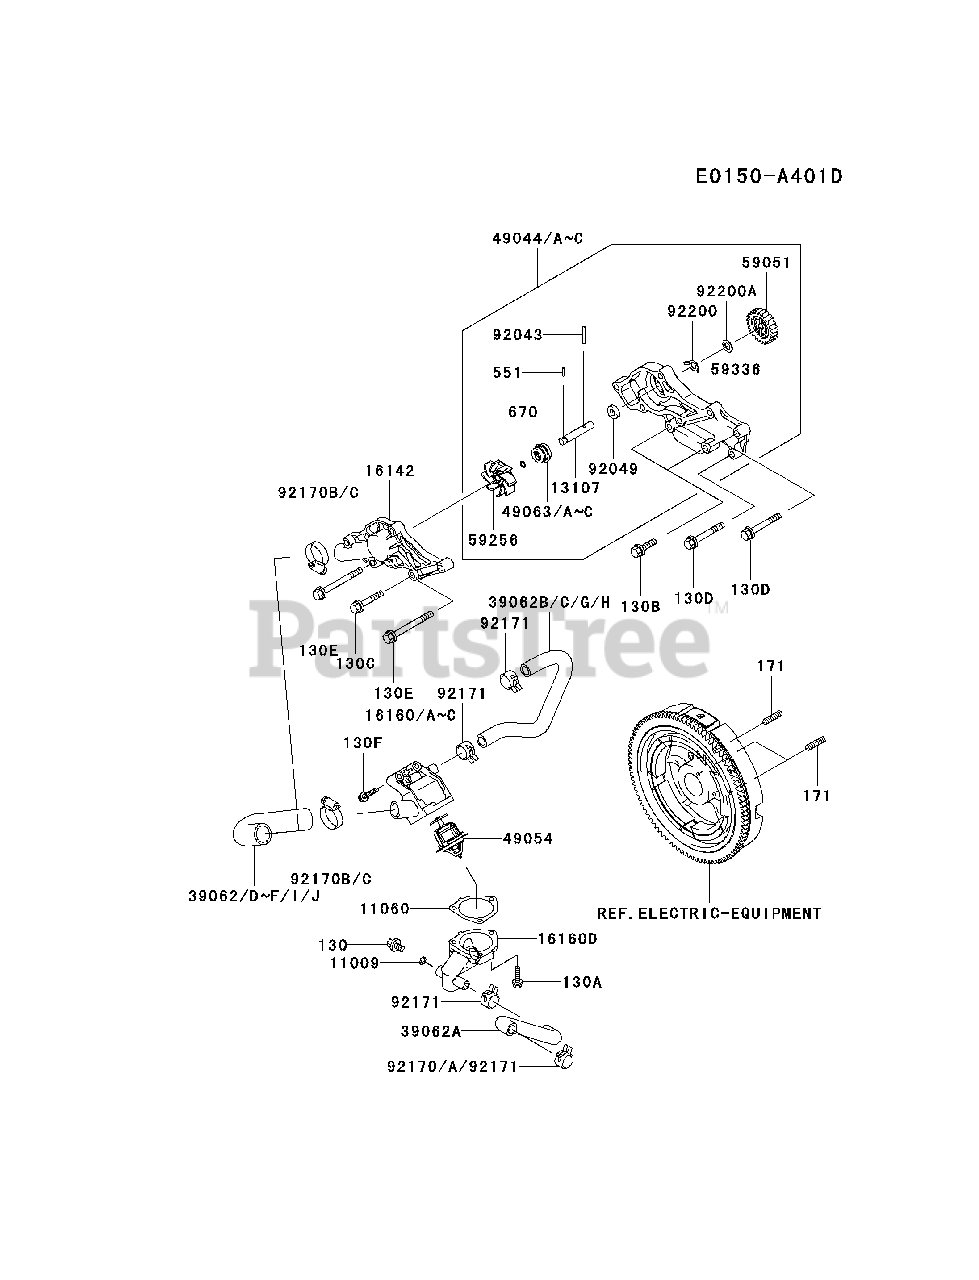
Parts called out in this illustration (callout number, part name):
130	BOLT-FLANGED,8X12
130A	BOLT-FLANGED,6X25
130B	BOLT-FLANGED,8X30
130C	BOLT-FLANGED,8X45
130D	BOLT-FLANGED,8X60
130E	BOLT-FLANGED,8X80
130F	BOLT-FLANGED,6X35
171	BOLT-STUD,8X18
551	PIN-DOWEL,3X14
670	O RING,7MM
92170C	CLAMP
92200A	WASHER,10.2X19X0.8
